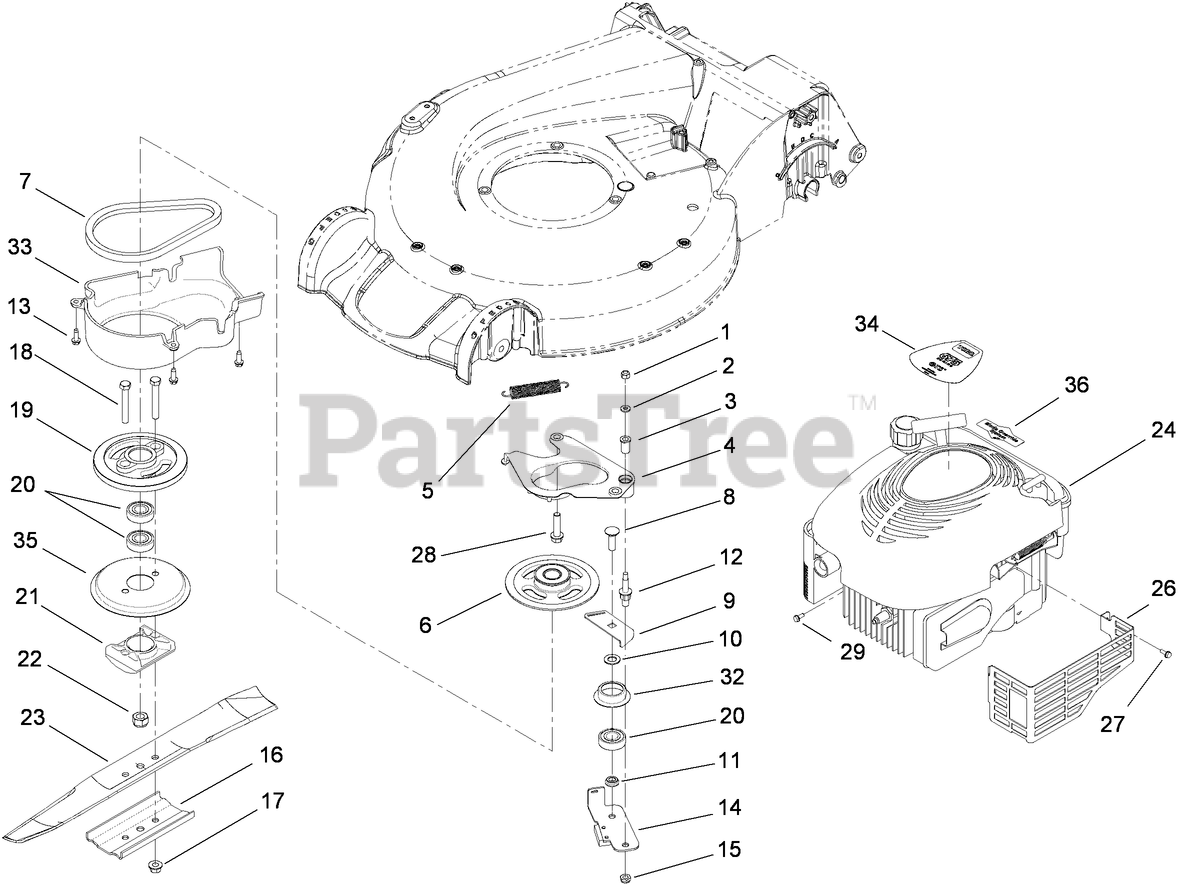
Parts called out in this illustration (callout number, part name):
1	NUT-LOCK, NI
2	WASHER-FLAT
3	BUSHING
4	PLATE-ANCHOR
5	SPRING-TENSION, BRAKE
6	PULLEY
7	BELT
8	BOLT-CARR
9	PLATE-GUIDE
10	SPACER
11	SPACER-BEARING
12	BOLT-SHOULDER
13	SCREW-HWHTF
15	LOCKNUT
16	SUPPORT-BLADE
17	NUT-LOCK
18	SCREW-HH
21	SUPPORT-BLADE
22	NUT-HEX
26	SHIELD-MUFFLER
27	SCREW-TAPTITE
28	SCREW-HWH
29	SCREW-HWH
32	RETAINER-BELT
34	DECAL-ENGINE
35	DISC
36	DECAL-RECOIL
